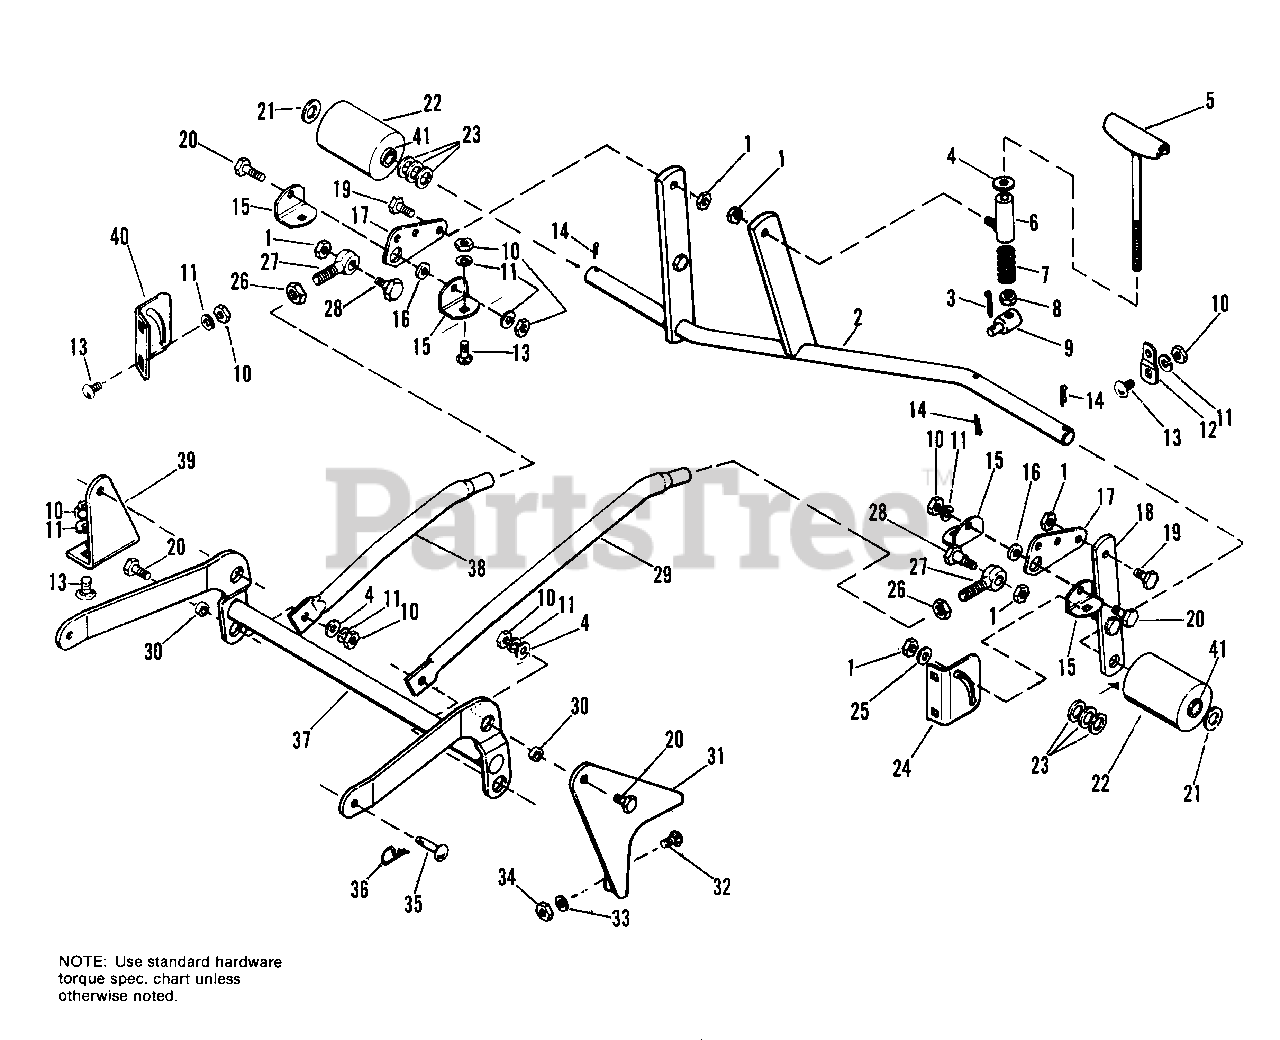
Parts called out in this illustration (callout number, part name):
1	LOCKNUT, Hex, 3/8-16
2	OLLER BAR & SHAFT ASSY.
3	PIN, Cotter, 3/32 x 3/4
4	WASHER, Plain, 3/8
5	SCREW ASSY., Adjusting
6	SOCKET ASSY., Crank
8	LOCKNUT, Jam, 3/8-16
10	NUT, Hex, Full, 3/8-16
11	LOCKWASHER, 3/8
13	BOLT, Carriage, 3/8-16 x 3/4
14	PIN, Cotter, 3/16 x 1
15	BRACKET, Pivot
17	LEVER, Rear
18	BAR ASSY., Roller
19	CAPSCREW, Hex Hd., 3/8-16 x 7/8
20	CAPSCREW, Hex Hd., 3/8-16 x 1
22	ROLLER ASSY.
24	BRACKET, Roller, L.H.
25	WASHER, Plain, 5/16
26	LOCKNUT, Jam, 1/2-20
28	BOLT, Shoulder
29	ARM, Adjusting, L.H.
31	BRACKET, Front, L.H.
32	BOLT, Carriage, 5/16-18 x 3/4
33	LOCKWASHER, 5/16
34	NUT, Hex, Full, 5/16-18
36	PIN, Quick
37	HITCH ASSY., Mower
38	ARM, Adjusting, R.H.
39	BRACKET, Front, R.H.
40	BRACKET, Roller, R.H.
